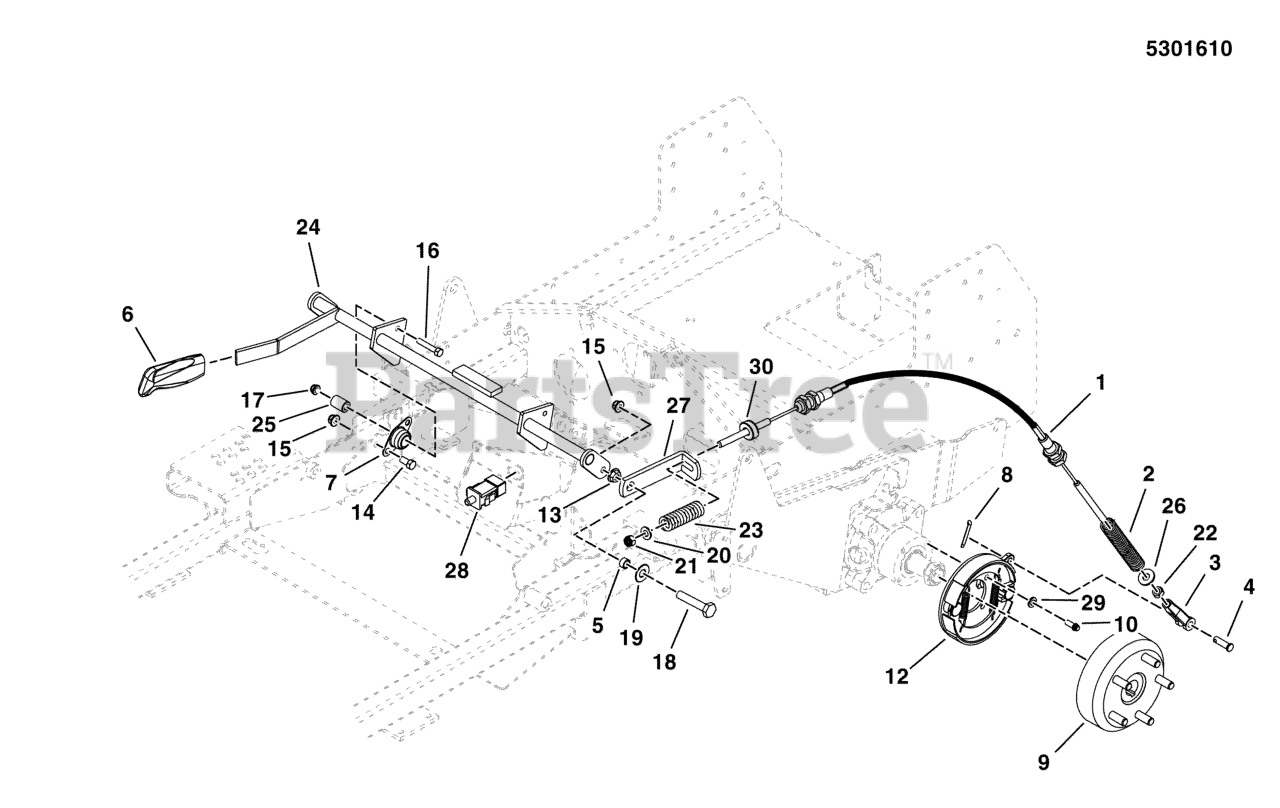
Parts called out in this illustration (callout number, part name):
3	CLEVIS, 5/16-24, STEEL, CLEAR ZINC
4	PIN-CLEVIS, 5/16 X 1 YZ
5	SPACER, .38 X .50 X .27
6	GRIP, BLACK FLEXIBLE
7	BEARING, BRONZE FLANGE, 3/4
8	PIN, HAIR, .0585 X 1-1/8, 1/4 EYE, YZ
10	BOLT-5/16-18 X 3/4 12PT FLNG-PATCH
13	NUT, 3/8-16 HEX JAM
14	BOLT, 3/8-16 X 3/4" GD5 CZ
15	NUT, 3/8-16 HEX NYLOCK FLANGE
16	BOLT, 5/16-18 X 1-3/4 GD5 YZ
17	NUT, 5/16-18 HEX NYLOCK FLANGE
18	BOLT, 3/8-16 X 1-1/2" GD5 CZ
19	WASHER, 3/8 SAE
20	WASHER, 5/16" SAE
21	NUT, 5/16-24 HEX NYLON LOCK
22	NUT, 5/16-24 HEX
23	SPRING, BRAKE
24	WELD, SHAFT, PARKING BRAKE - BLK
25	SPACER, .32 X .75 X 1.06
26	WASHER, 5/16 USS
27	LINK, BRAKE LOCK - BLK
28	SWITCH, DP NO/NC SNAP-IN
29	WASHER, 5/16 LOCK CZ
30	COLLAR, 5/16 SET
